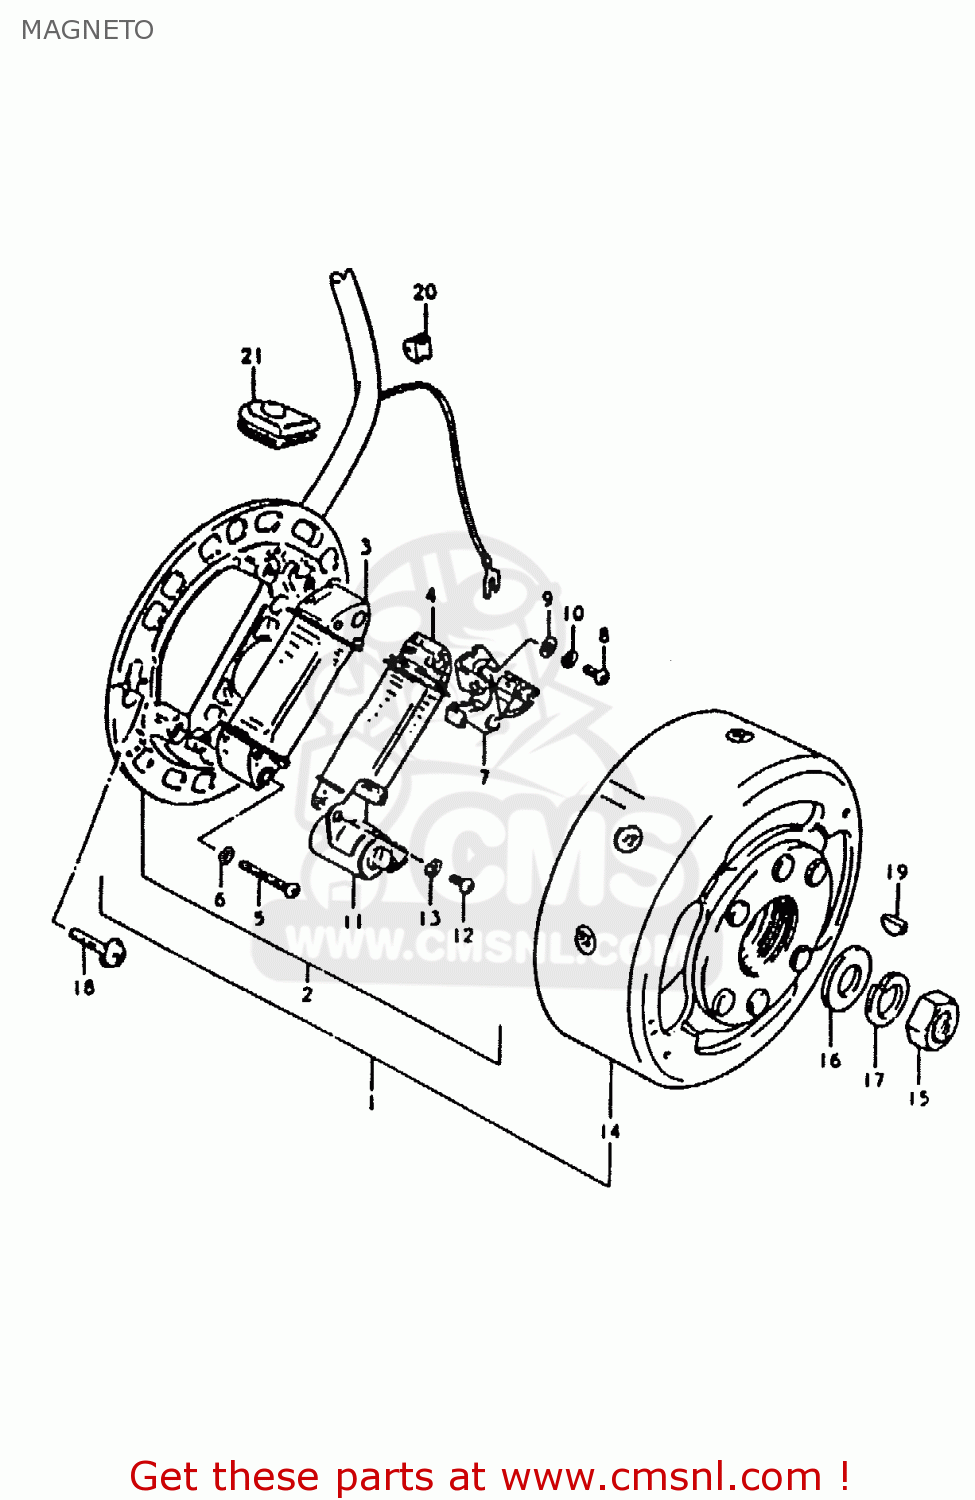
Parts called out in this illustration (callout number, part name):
1	MAGNETO ASSY
2	STATOR ASSY
3	COIL, LIGHTING
4	COIL,PRIMARY
5	SCREW (4X30)
6	LOCK WASHER
7	POINT ASSY,CONTACT
8	SCREW(4X10)
9	WASHER
10	LOCK WASHER
11	CONDENSER
12	SCREW
13	LOCK WASHER
14	ROTOR ASSY
15	NUT (10MM)
16	WASHER
17	LOCK WASHER
18	SCREW(5X14)
19	KEY
20	GROMMET,NEUTRAL LEAD WIRE
21	GROMMET
